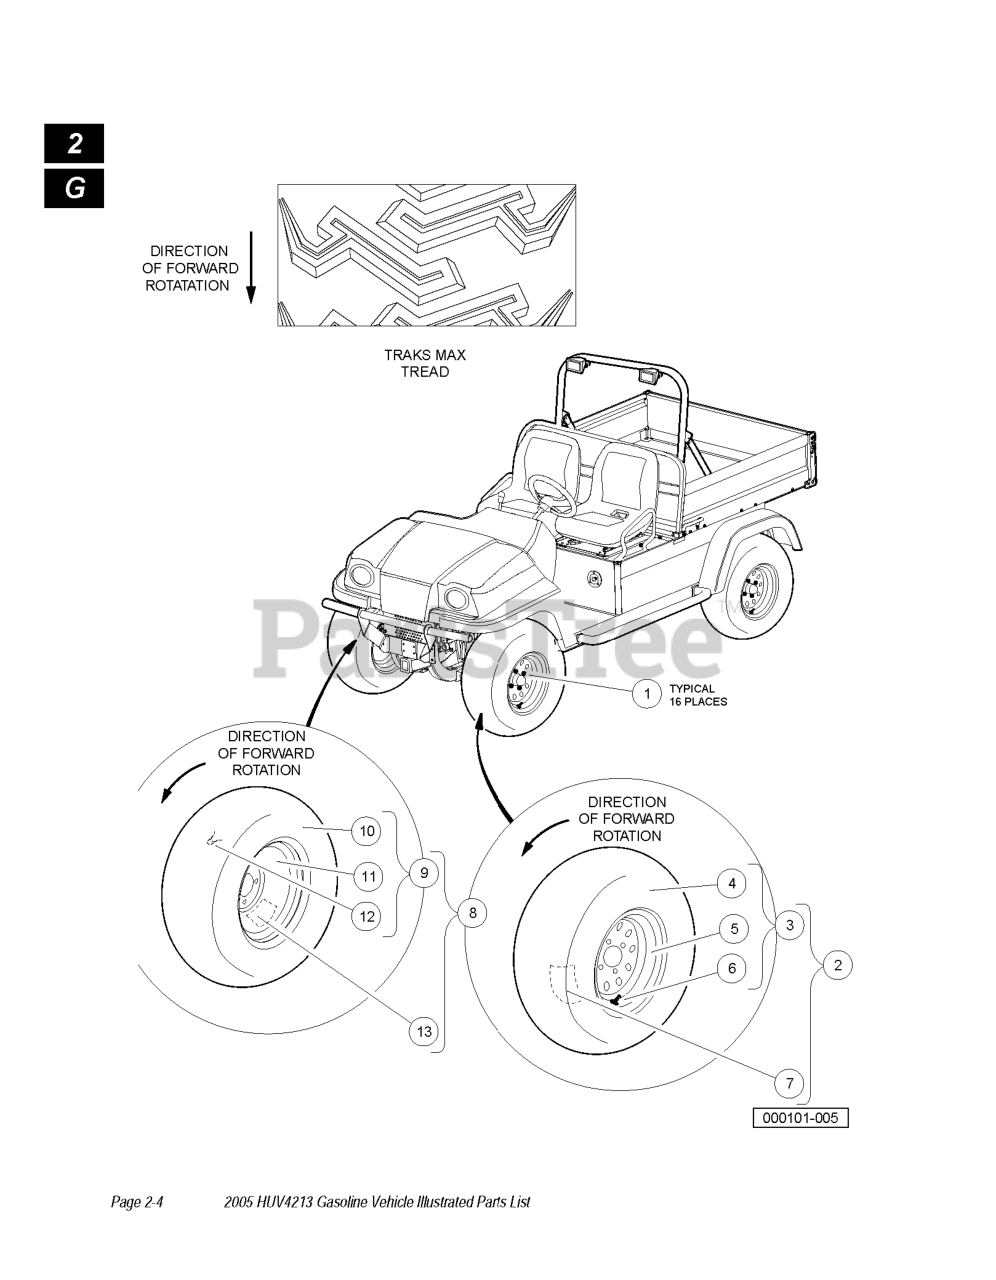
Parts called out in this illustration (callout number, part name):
1	NUT 1/2-20 LUG
2	Tire Asm, Traks Max L Service
4	TIRE-TRAKS MAX II
5	WHEEL RIM 10" GRAY
7	BRAKE WARNIN DECAL
8	Tire Asm, Traks Max R Service
10	TIRE-TRAKS MAX II
11	WHEEL RIM 10" GRAY
13	BRAKE WARNIN DECAL
